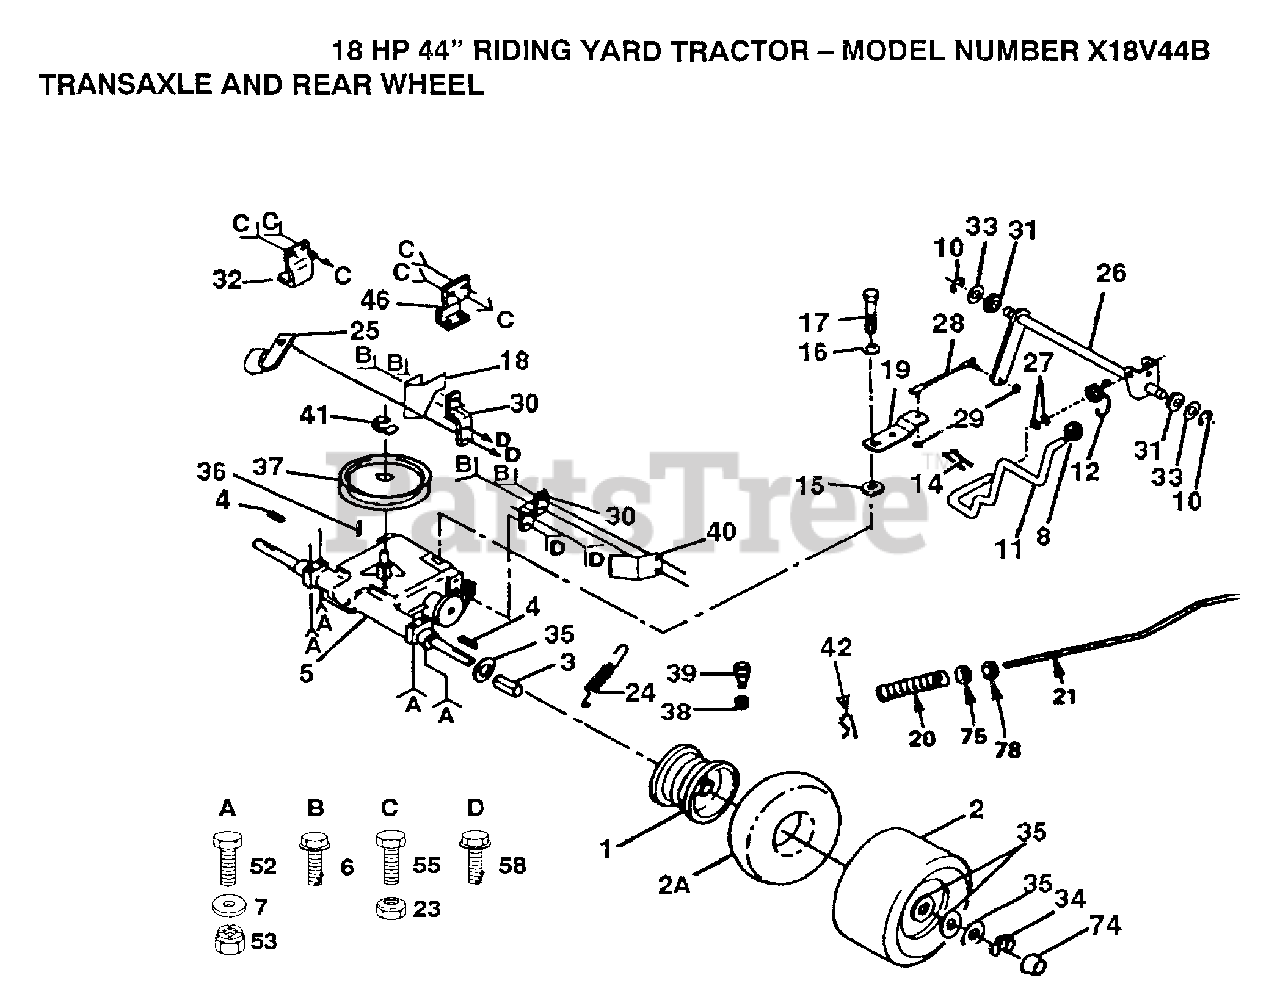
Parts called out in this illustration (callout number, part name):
2A	TUBE.23X8/10-12
3	SPACER HYT
4	SQ KEY STD
5	TRANSAXLE PEERLESS MODEL NO
6	SCREW
7	WASHER
8	KNOB T (1/2-HOLE)
9	COTTER PIN
10	KLIP RING
12	"SPRING,TORSION"
14	PIN COTTER 1/8
15	WASH-SHFT PLT LT
16	WASHER PM
18	KEEPER BELT LH
19	"ARM,SHIFT"
20	"SPRING,ROD BRAKE"
21	ROD BRAKE
22	WASHER
25	CLIP T
26	"SHAFT,SHIFTER"
27	WASHER
28	"ROD,TIE "
29	NUT 1/4-28
30	STRAP TORQUE
31	BUSHING
32	BRKT TRANS LH
33	WASHER D
34	E RING HYT
35	WASHER
37	PULLEY TRANSAXLE
38	VALVE CAP
39	VALVE STEM LT
40	"KEEPER,BELT RH"
41	RING
42	RETAINER M
46	BRKT TRANS RH
52	BOLT HEX
58	SCREW
74	HUB CAP
75	NUT
78	NUT
